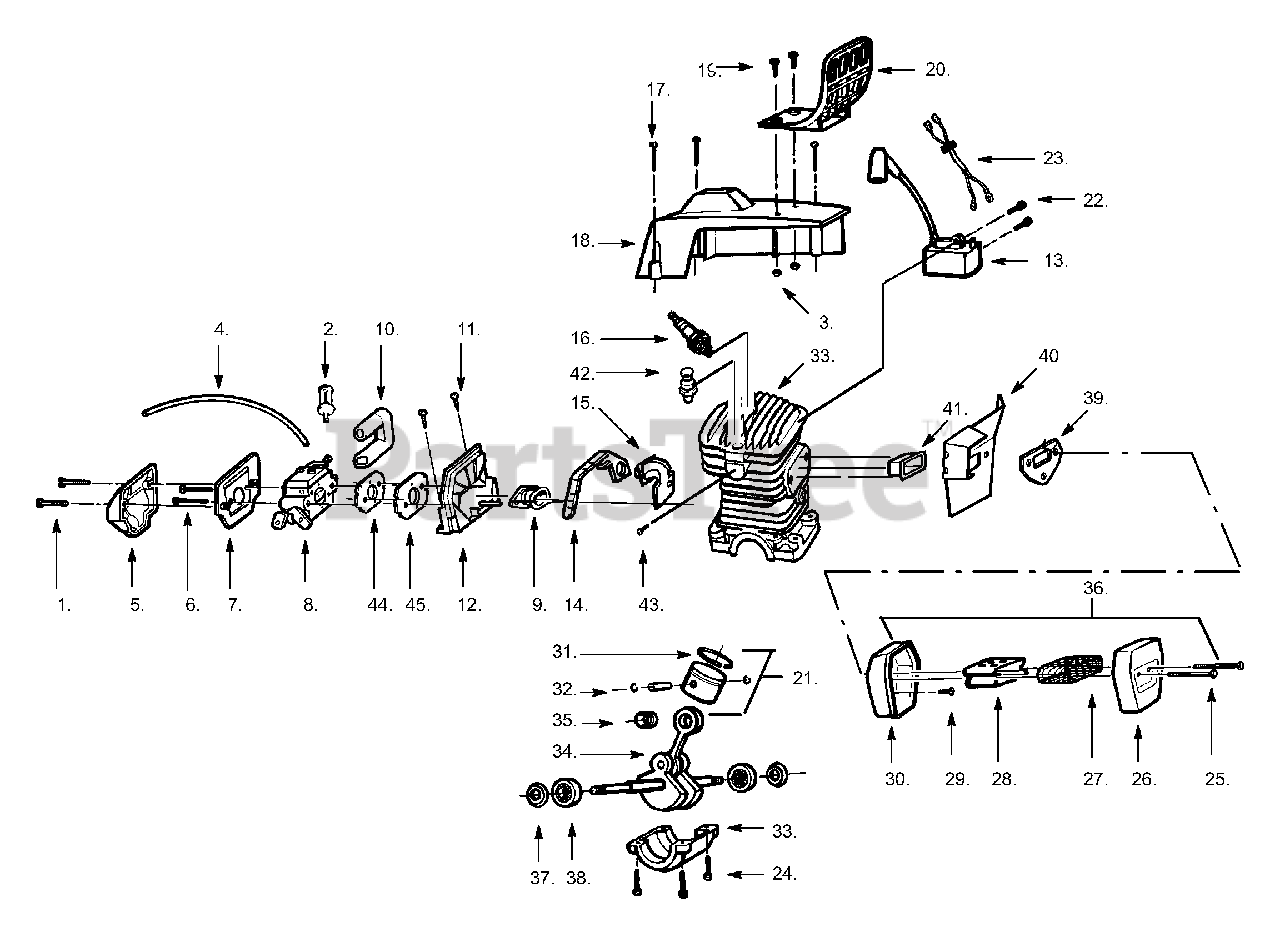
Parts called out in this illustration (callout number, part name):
2	Fuel Pick-up
3	Nut
4	Fuel Line
5	Air Filter (Top)
7	Air Filter (Bottom)
8	Carburetor (WT-285)
9	Intake Boot
10	Carb. Grommet
11	Screw
12	Carb. Adaptor
13	Ignition Module
14	Turbo Clean Seal
15	Turbo Air Cleaner Ass'y.
16	Spark Plug (CJ-7Y)
17	Screw
18	Cylinder Shield Decal (Not a serviceable part)
19	Screw
20	Handguard
21	Piston Kit
23	Switch Wire Ass'y.
25	Muffler Bolt
26	Muffler Cover
27	Spark Screen
28	Diffuser
30	Muffler Body
31	Piston Ring
32	Piston Pin Retainer
34	C'shaft & Rod Ass'y.
35	Piston Pin Bearing
36	Muffler Kit
37	C'shaft Seal
38	C'shaft Bearing
39	Muffler Gasket
40	Muffler Plate
41	Heat Insulator
42	Decompression Valve
43	Plug-Cylinder Screw
44	Carburetor Gasket
45	Carburetor Plate
